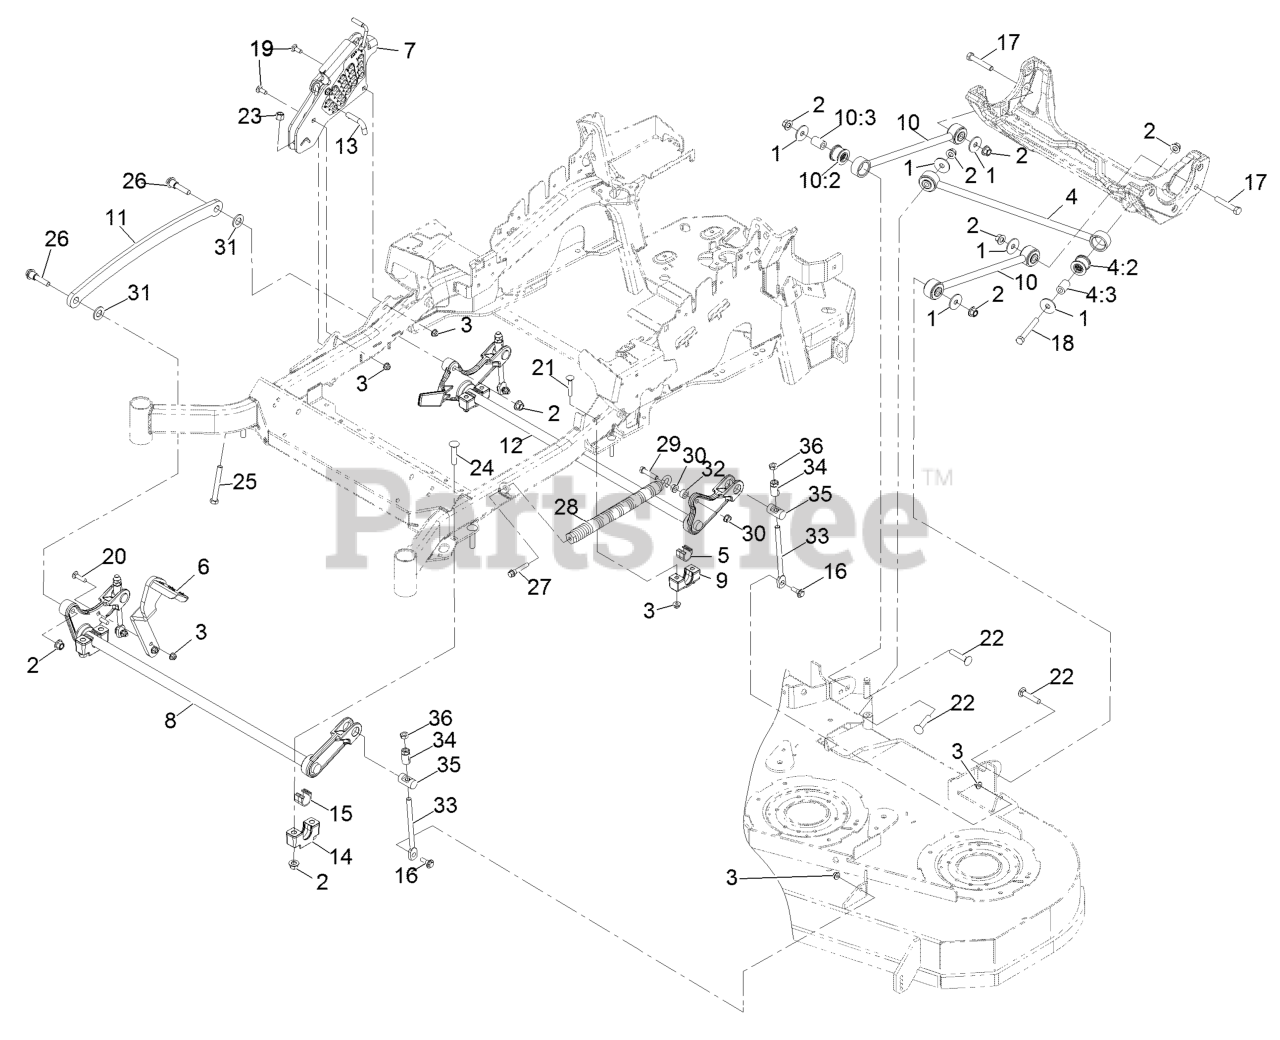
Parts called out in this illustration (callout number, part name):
1	WASHER-THRUST
2	Nut-Lock 1/2-13
3	NUT-HF, NI
4	PANHARD ROD ASM
4:2	BUSHING-SUSPENSION, RUBBER
5	BEARING-CROSS SHAFT, REAR
6	LEVER-FOOT
7	HOC ASM
8	DECKLIFT-FRONT
9	SUPPORT-CROSS SHAFT, BEARING REAR
10	DECK STRUT ASM
10:2	BUSHING-SUSPENSION, RUBBER
11	LINK-LIFT, DECK
12	LIFT-DECK, REAR
13	PIN-HOC
14	SUPPORT-CROSS SHAFT, BEARING
15	BEARING-CROSS SHAFT, FRON
16	SCREW-SHOULDER, HHF
17	SCREW-HH
18	SCREW-HH
19	BOLT-CARR
20	SCREW-CARR
21	Bolt-Carriage 3/8-16 X 2 1/4
22	SCREW-CARR
23	NUT-LOCK, NI
24	Bolt-Carriage 1/2-13 X 2 1/2 Spl Neck
25	BOLT-TAP
26	SCREW-HHF, SHOULDER
27	BOLT-SHOULDER
28	SPRING-EXTENSION
29	SCREW-HH
31	WASHER-FLAT
33	LINK-ADJUSTER, DECK LIFT
34	ADJUSTER-LIFT, DECK
35	TRUNNION
36	NUT-JAM
